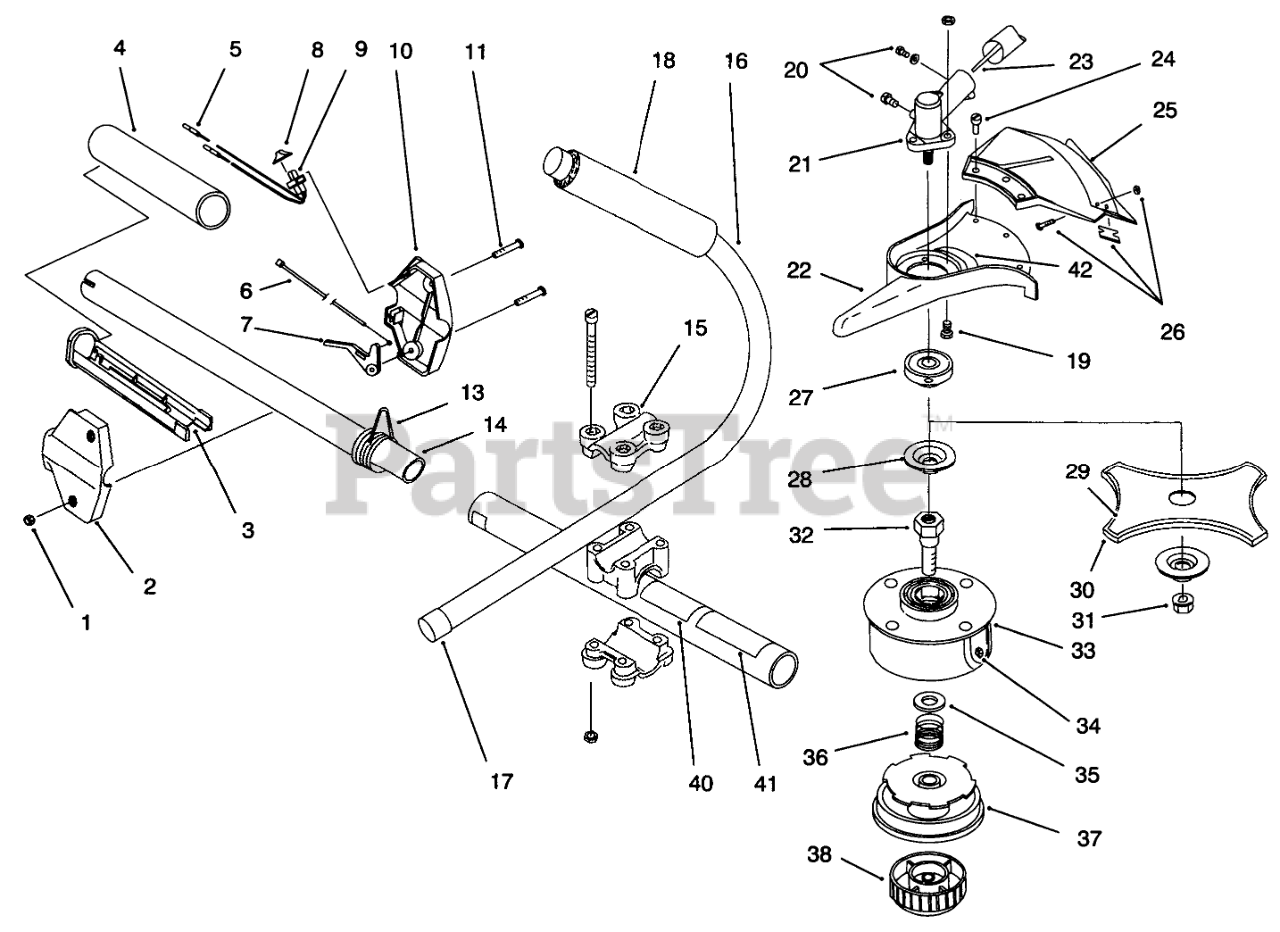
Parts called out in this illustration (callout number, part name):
1	NUT-LOCK, NI
2	RH HOUSING
3	TROUGH 1"
4	GRIP - RUBBER
5	LEAD WIRE ASM
6	THROTTLE CABLE
7	THROTTLE LEVER
8	SWITCH COVER
9	SWITCH
10	LH HOUSING
13	Clip-Shoulder Strap
14	ASM - DRIVE SHAFT HSG
15	Handle Bracket Asm. (Incl.4 Screws & 4 Nuts)
16	J-Handle Asm. (Incl. Ref. #17-18)
17	TUBE CLOSURE
18	HANDLE NITRILE GRIP
19	SCREWS - GUARD MOUNTING
20	MTG HDW&PLUG SET
21	ASSEMBLY - GEAR BOX
22	GUARD MOUNT
23	FLEXIBLE DRIVE SHAFT
24	GUARD MNTG SCREW ASM
25	GUARD & BLADE ASM
26	Blade Asm.
27	BLADE DRIVER
28	Blade Retaining Washer
29	BLADE SAFETY GUARD
30	Blade (Incl. Ref. #29)
31	BLADE RETAINER NUT
32	SPOOL SHAFT
33	Outer Spool & Eyelet Asm.
34	EYELET
35	RETAINER ( 10 PACK)
36	SPRING
37	INNER REEL
38	BUMP HEAD KNOB ASSEMBLY
40	Decal-Safety Symbol
41	DECAL - SAFETY
42	DECAL - WARNING
